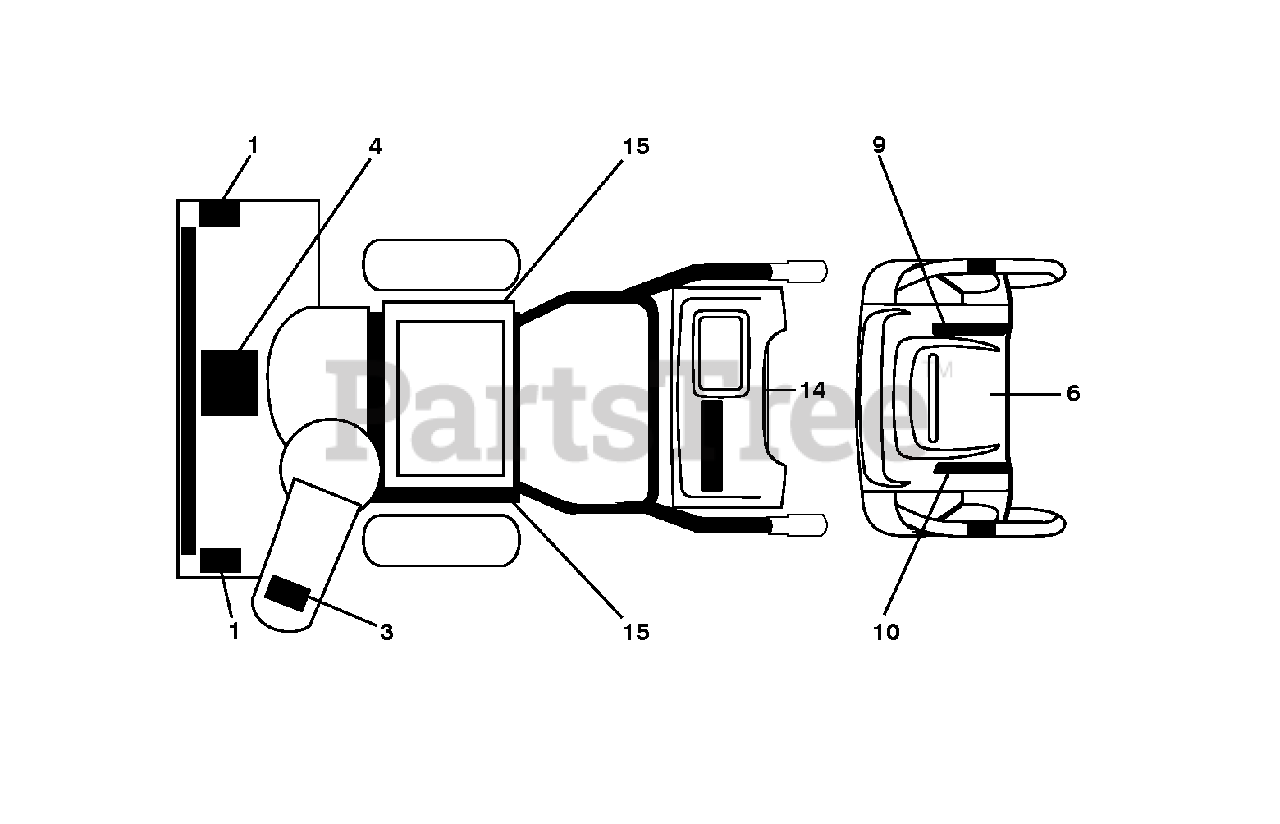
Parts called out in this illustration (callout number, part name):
1	DECAL.AUGER.SAFETY.
3	DECAL.CHUTE.SAFETY.
4	DECAL.AUGER."
6	DECAL.CONSOLE.INSTRUCTION
9	DECAL.CONS.RT.SPD/LEV/PWRST
14	DECAL.FENDER
15	DECAL.BELT.GUARD.
